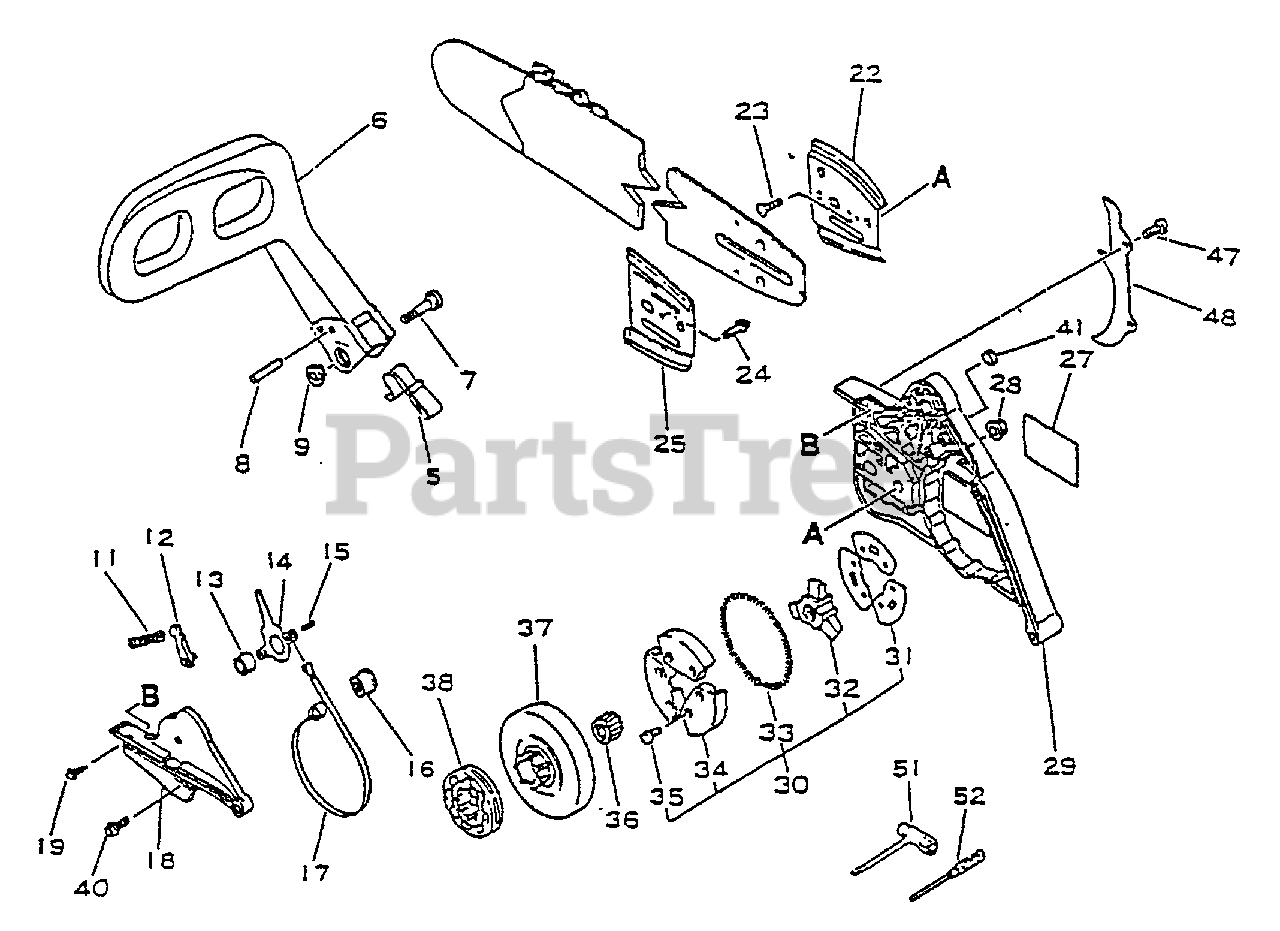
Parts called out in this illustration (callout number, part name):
5	SPRING, RETURN
6	LEVER, BRAKE
7	MOUNTING KIT
8	PIN 3.5×26
11	SPRING, BRAKE
12	STOPPER, BRAKE
13	SPACER 8×12×9
14	LEVER, BRAKE
15	PIN, SPRING - 4×8
16	ADJUSTER, BRAKE
17	BAND, BRAKE
18	COVER, BRAKE
19	SCREW 4×12
22	PLATE, GUIDE - OUTER
23	SCREW 3×6
24	SCREW 4×8
25	PLATE, GUIDE - INNER
27	LABEL, ECHO
28	NUT, FLANGE M8×1.25
29	GUARD, SPROCKET
30	CLUTCH ASSY
31	PLATE, CLUTCH
32	HUB, CLUTCH
33	SPRING, CLUTCH
34	SHOE SET, CLUTCH (3PCS)
35	BOLT 4×6
36	BEARING, NEEDLE
37	DRUM, CLUTCH
38	SPROCKET, 0.325 RIM
40	SCREW 3×18
41	NUT 3 MM
48	SPIKED BUMPER KIT
51	T-WRENCH 13×19×180
52	SCREWDRIVER, PHILLIPS
